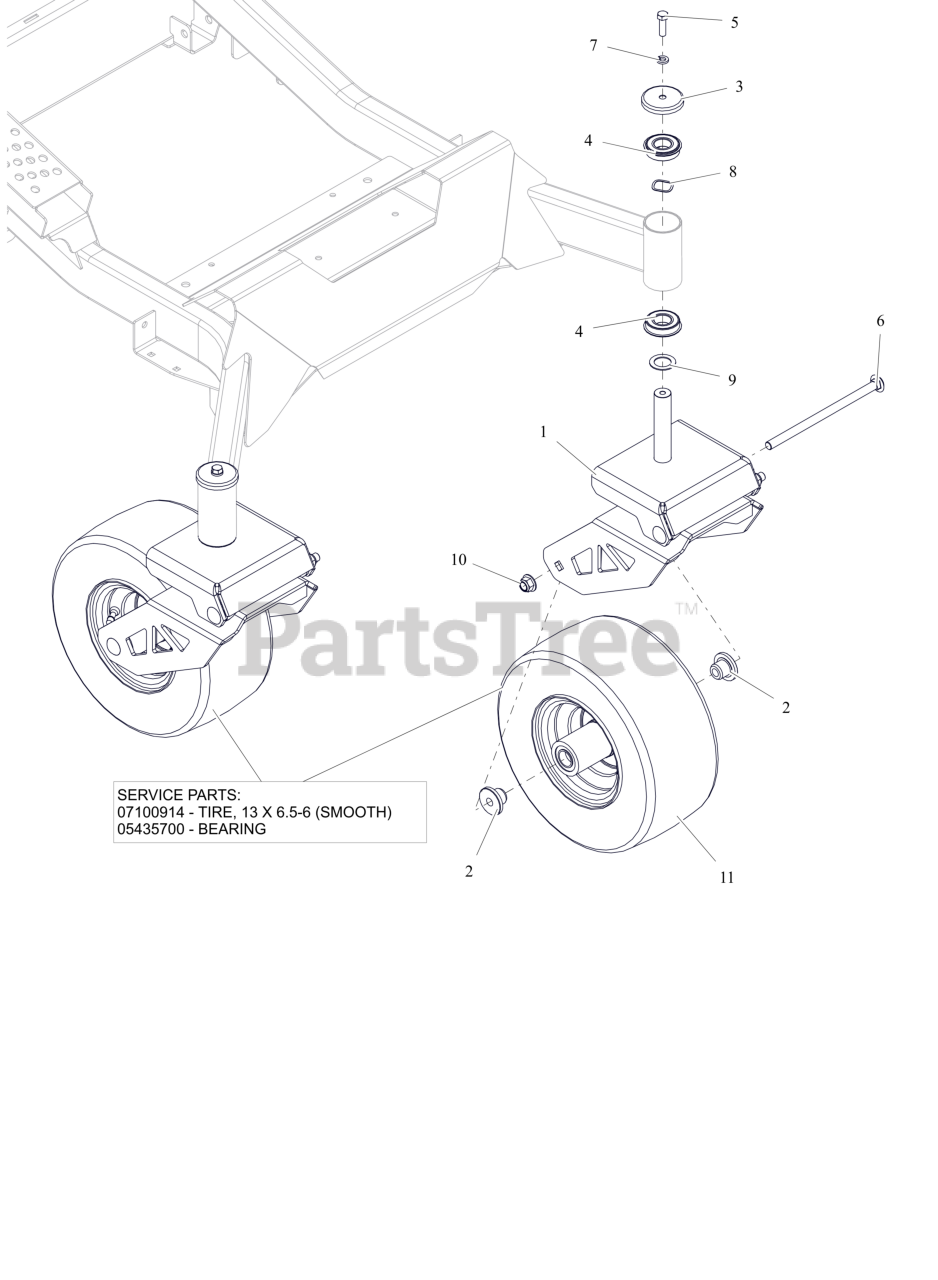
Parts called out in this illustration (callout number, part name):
1	ASM, SUSPENSION FORK
2	SPACER, FRONT WHEEL
3	SHIELD, AXLE BEARING
4	BEARING, BALL -2.000 OD X 1.000 ID X .5625 W/RING
5	BLT, HEX .38-16X1.25 G5 ZCC
6	BLT, RHSN .50-13X9.00 G5 ZCC
7	WSHR, LK-HVY .375X.115 ZCC
8	WSHR-WAVE 1.0X1.25X.028 .145FH
9	WSHR-HRD-THRS 1.007X1.542X.062
10	NUT,NYL-FLG .50-13 GF ZCC
11	ASM, WHL/TIRE 13X6.50-6
11	LAWN TIRE FRONT, 13X6.50-6 SMOOTH
11	BRG, 25MM ID X 52MM OD X 15MM
11	TIRE TUBE, 13/6.5-6 4 PLY TR87 90 BENT VALVE
